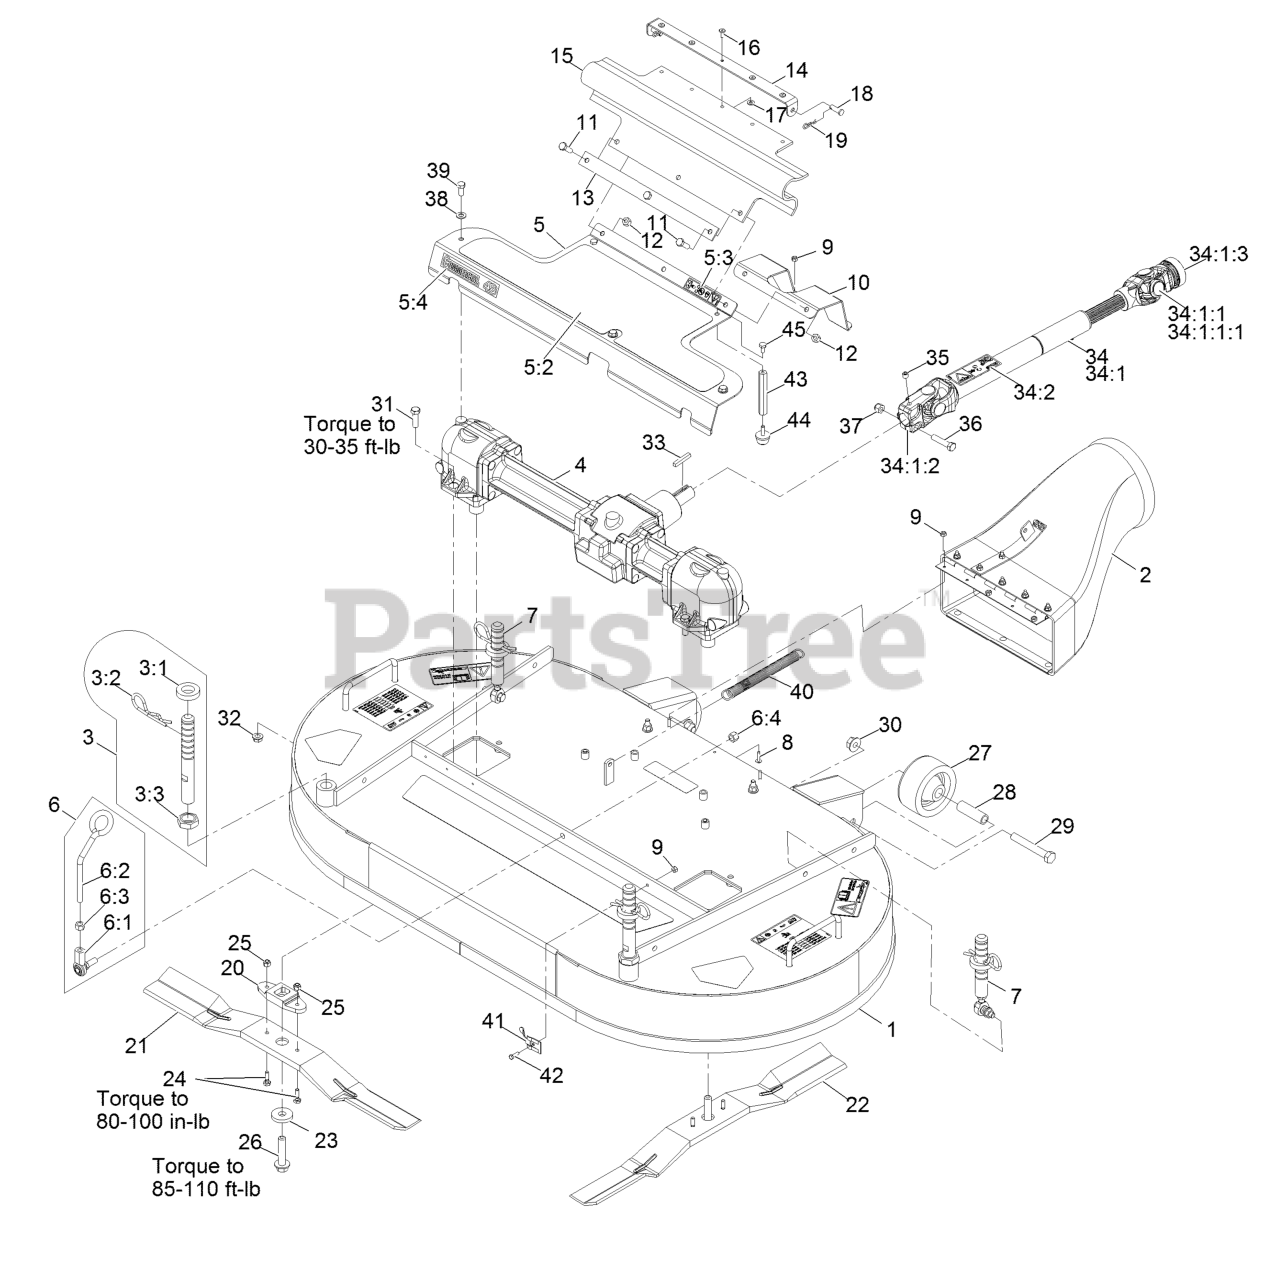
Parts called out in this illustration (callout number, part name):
1	DECK DECAL AND BAFFLE ASM
2	DISCHARGE TUBE ASM
3	FRONT DECK HEIGHT ADJUST
3:1	SPACER-DECK SUPPORT
3:2	PIN-CUT HEIGHT
3:3	NUT-JAM
4	GEAR BOX ASM
5	ASM,GEARBOX COVER 48 W/DE
5:2	PAD-ANTI SKID
5:3	DECAL-DANGER
5:4	DECAL,COMMERCIAL 48
6	DECK LATCH ASM
6:1	BALLJOINT-RH
6:2	LATCH-DECK
6:3	NUT-HEX
6:4	NUT-LOCK
7	REAR DECK HEIGHT ADJUST A
8	SCREW-HEAD, TRUSS
9	NUT-LOCK, NI
10	GUARD-DRIVE SHAFT
11	SCREW-HH
12	NUT-LOCK, NI
13	STRAP-DRIVE, LINE COVER
14	BRACKET-GUARD, PTO
15	GUARD-PTO
16	RIVET-BLIND
17	WASHER-FLAT
18	PIN-CLEVIS
19	PIN-COTTER
20	DRIVER-BLADE
21	BLADE,25 INCH RH
22	BLADE,25 INCH LH
24	BOLT-SHEAR
25	NUT-LOCK, NI
26	BOLT-BLADE
27	ROLLER-DECK
28	SPACER-ROLLER
29	SCREW-HH
30	NUT-HHF
31	SCREW-HH
32	NUT-HHF, WHIZ
33	KEY-SQUARE
34	DRIVE SHAFT ASM
34:1	Drive Shaft-Telescoping
34:1:1	U-JOINT KIT
34:1:1:1	FITTING-GREASE
34:1:2	YOKE-KEYED
34:1:3	YOKE-QUICK DISCONNECT
34:2	DECAL-DANGER, DRIVELINE
35	SCREW-SET, HSH
36	SCREW-HH
37	NUT-LOCK, NI
38	WASHER-PLAIN
39	SCREW-HH
40	SPRING-EXTENSION
41	CLIP-DECK, HOLD UP ROD
43	STAND-OFF
45	SCREW-HH
